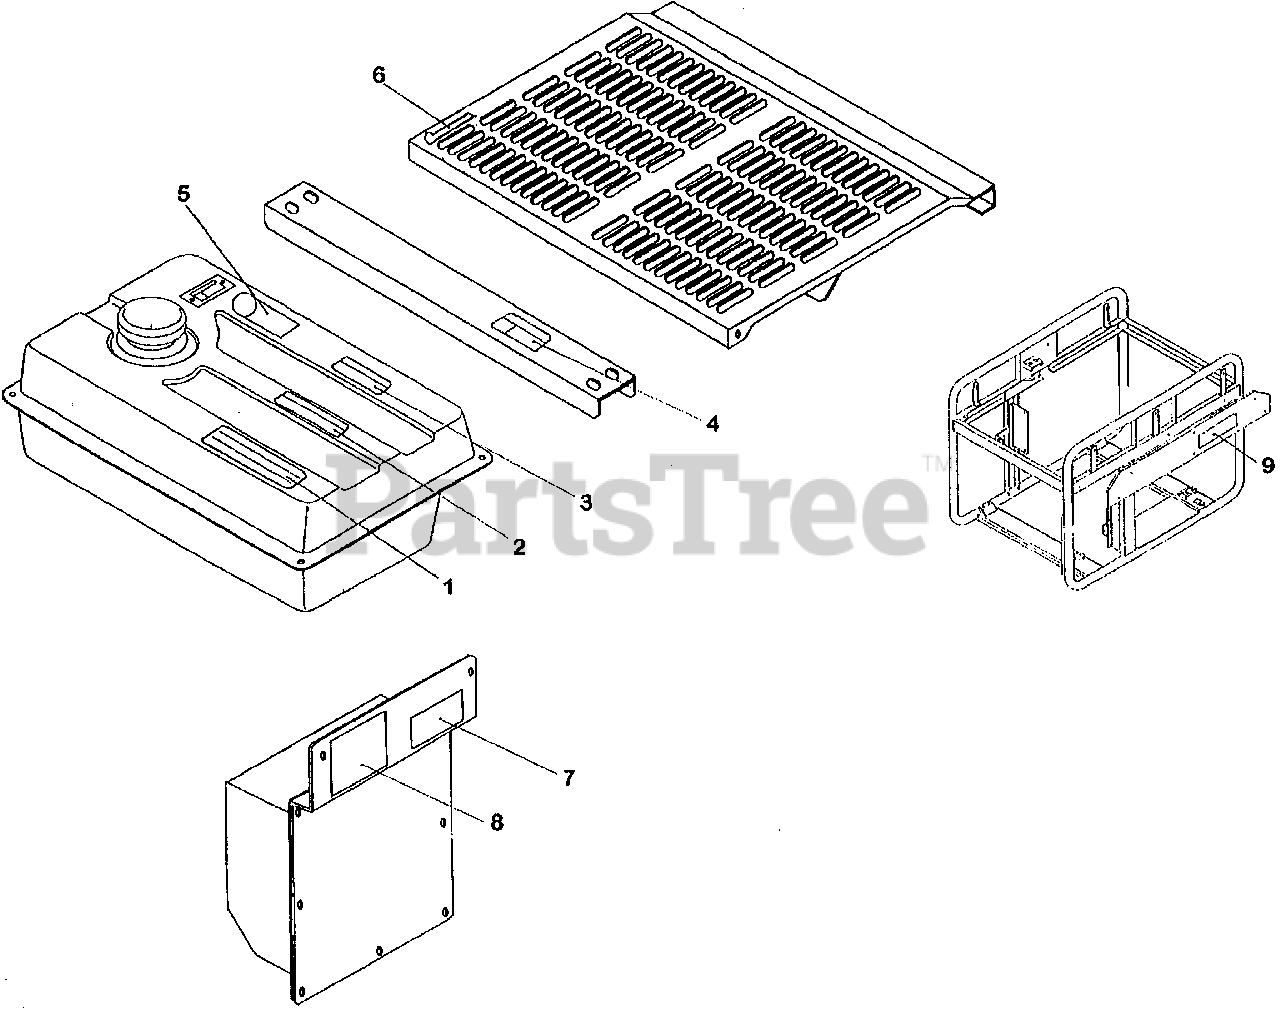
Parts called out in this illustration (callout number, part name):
1	MARK, CAUTION (CO)(ENGLISH/FRENCH)(SPANISH)
2	LABEL, CONNECT WARNING (ENGLISH)
3	LABEL, RAIN WARNING (ENGLISH)
4	MARK, EX. WARNING (ENGLISH/FRENCH)
5	MARK, CAUTION (ENGLISH/FRENCH)(SPANISH)
6	MARK, EX. CAUTION
7	PLATE, CAUTION
8	MARK (TEST RECORD)
9	MARK, EMBLEM
